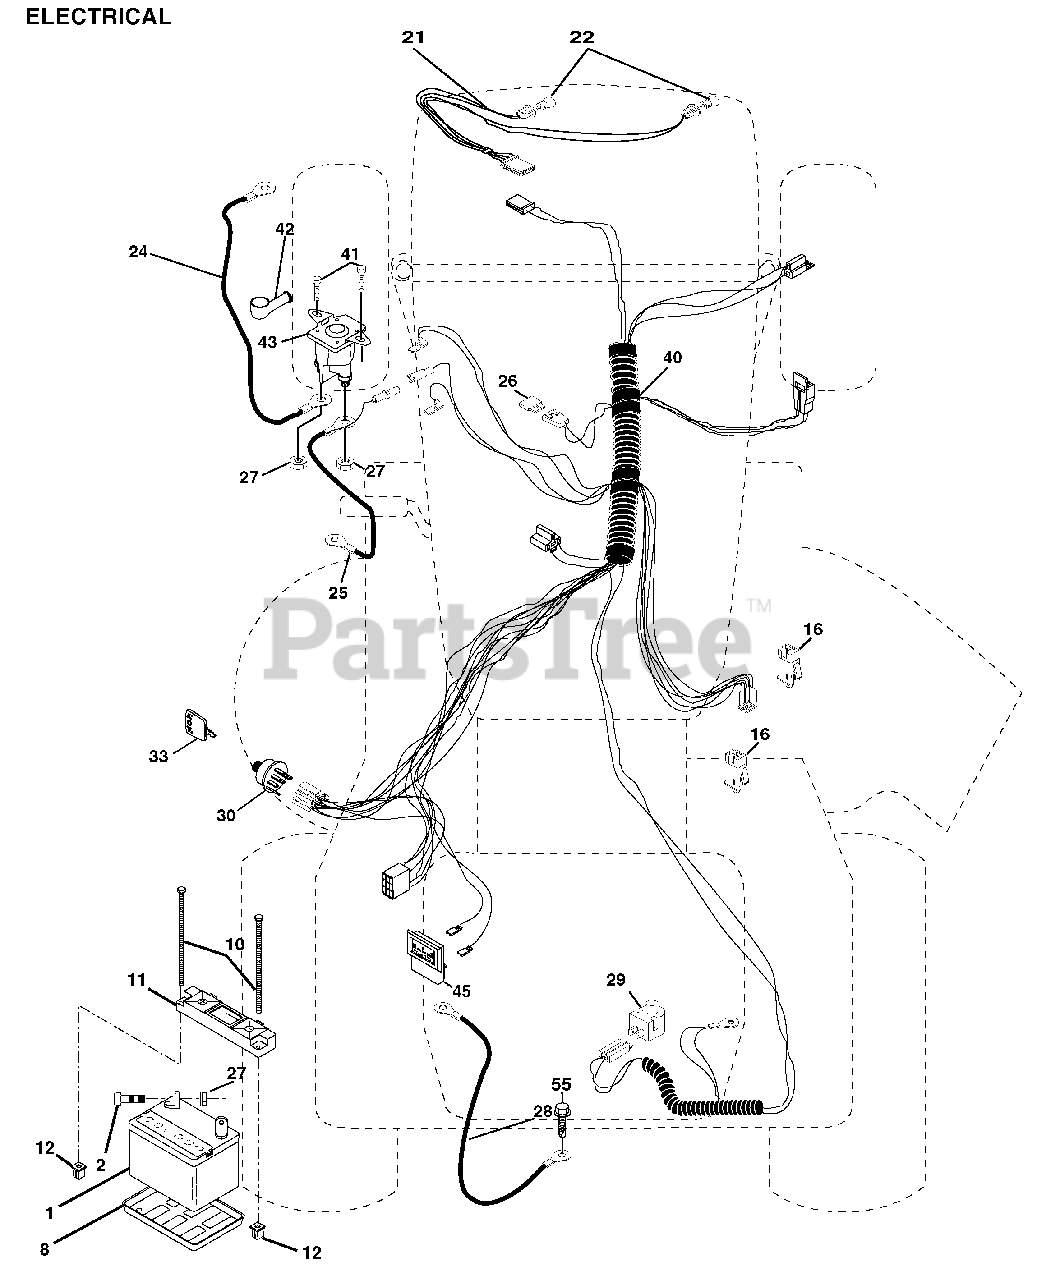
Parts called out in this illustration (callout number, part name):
1	Battery, 12 Volt, 28 Amp
2	Bolt, Hex Head 1/4-20 UNC x 3/4
8	Tray, Battery
10	Bolt, Battery Front 1/4-20 x 7.5 Zinc
11	Holddown Battery Dash Mount
12	Nut, Push Nylon 1/4" Battery Front
16	Switch Interlock Push-In
21	Harness, Light
22	Bulb, Light
24	Cable, Battery
25	Cable, Battery
26	Fuse, 20 Amp
27	Nut, Hex, Keps 1/4-20 UNC
28	Cable, Ground, 6 Gauge, 12", Black
29	Switch, Plunger
30	Switch, Ignition, Push-In
33	Key, Ignition
40	Harness, Ignition
41	Bolt, Hex, Fin. 1/4-20 x 1/2
42	Cover, Terminal, Red
45	Ammeter, Rectangular
55	Screw, Thdrol 5/16-18 x 1/2 TYT
